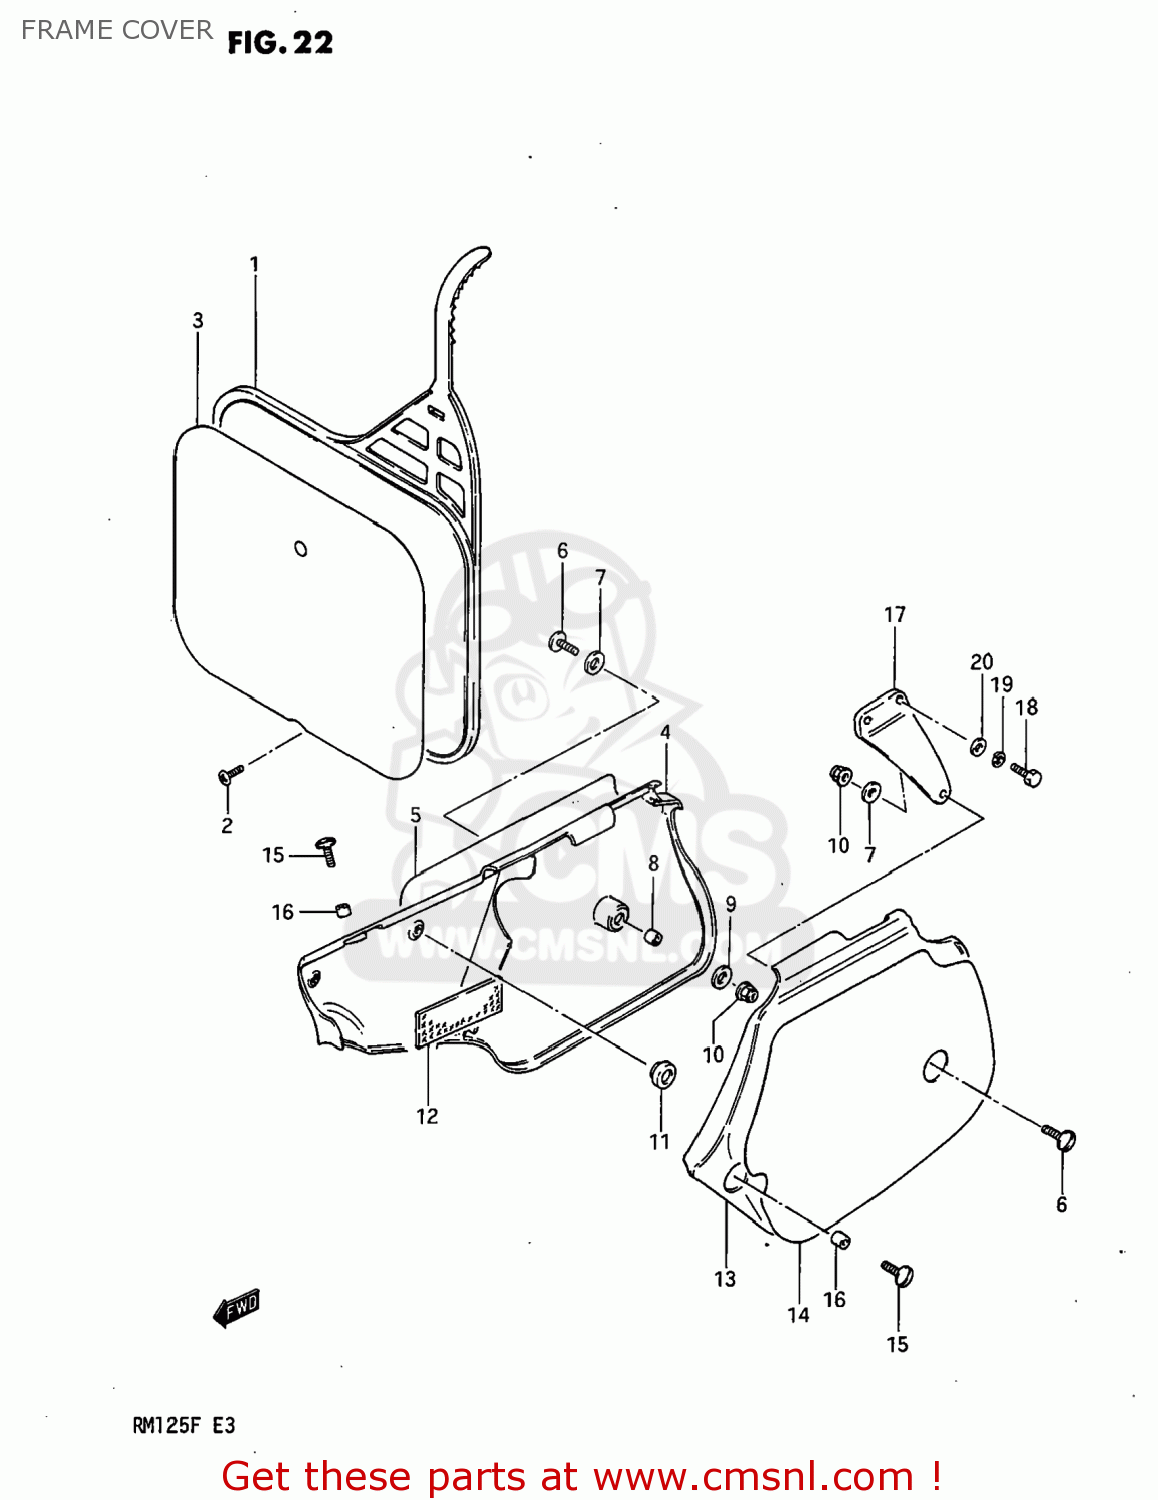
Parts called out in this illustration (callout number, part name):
1	PLATE,NUMBER,FRONT
2	SCREW
3	TAPE,FRONT NUMBER PLATE
4	COVER,FRAME,RIGHT
5	EMBLEM,NUMBER PLATE,RIGHT
6	SCREW(6X20)
7	WASHER FRAME COVER
8	SPACER
9	GASKET
10	NUT
11	CUSHION
12	HEAT SHIELD,FRAME COVER
13	COVER,FRAME,LEFT
14	EMBLEM,NUMBER PLATE,LEFT
15	SCREW(6X14)
16	SPACER (6.1X8X3.5)
17	STAY,FRAME COVER,LEFT
18	BOLT
19	WASHER,LOCK
20	WASHER(6.5X16X1.2)
